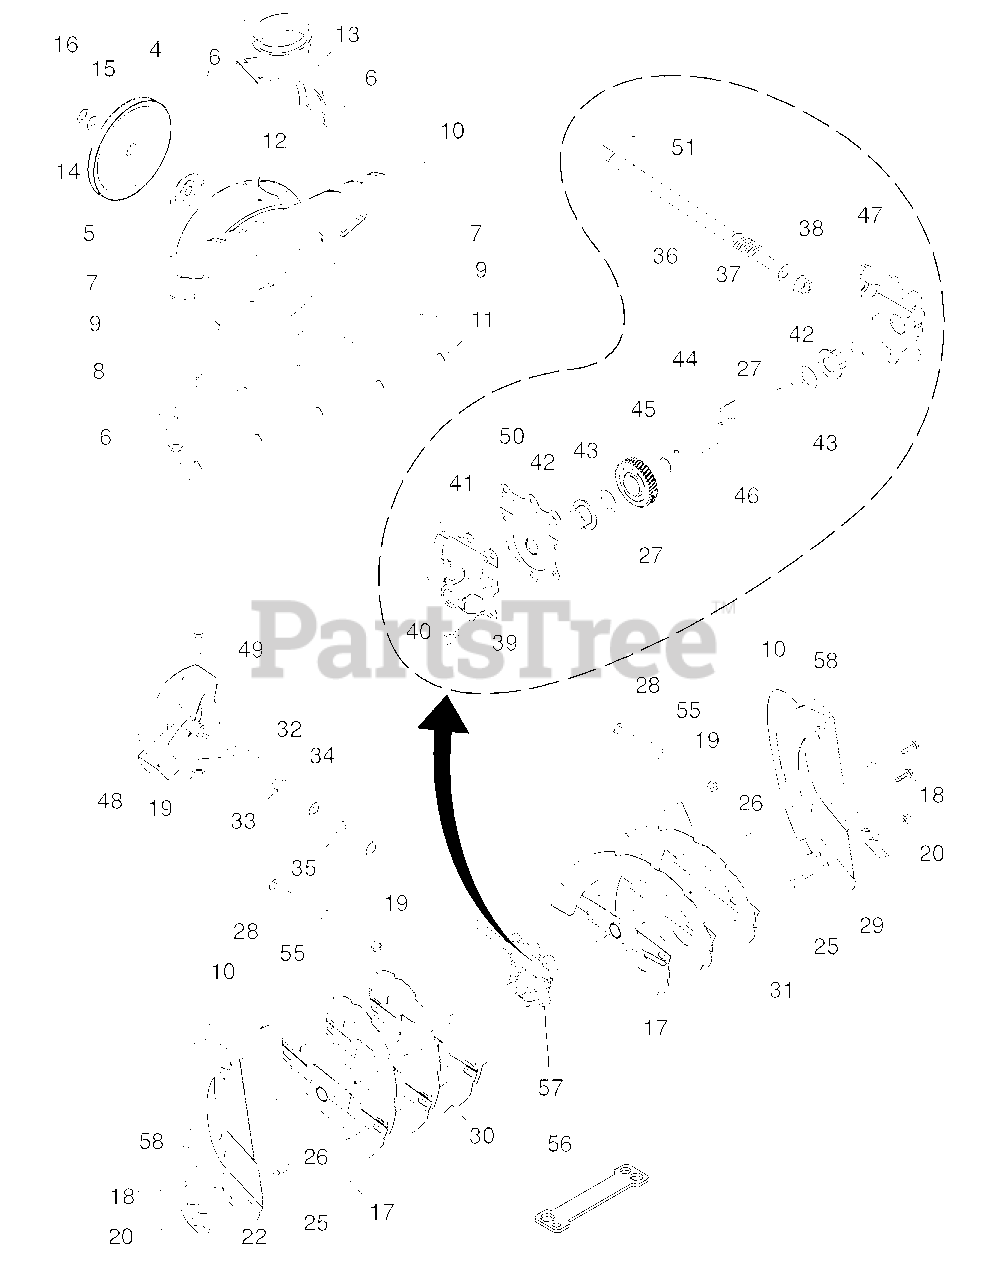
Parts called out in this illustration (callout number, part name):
1	Knob, Lever
2	Screw #10-24 x 5/8
3	Strap, Slotted
4	Nut, Lock 3/8-16
5	Washer, Flat 3/8
6	Control Assembly, Chute Rotater
7	Support, Pivot
8	Screw, Hex Head 5/16-18 x 3/4
9	Knob, Deflector
10	Bolt, Shoulder
12	Nut, Lock 1/4-20
13	Bolt, Carriage 5/16-18
14	Washer, Nylon, Friction
15	Chute Assembly
16	Deflector Assembly
17	Seal, Deflector
18	Rivet, Blind
19	Knob, Speed Control Lever
20	Bolt, Carriage 5/16-18 x 3/4
21	Washer, Flat 5/16
25	Nut, Lock 5/16-18
26	Lever Assembly, Speed Control
27	Retainer, Hairpin
28	Rod, Upper, Speed Control
29	Rod, Lower, Speed Control
30	Clamp, Clean-Out Tool
31	Tool, Clean-Out
33	Washer, Nylon, Friction
34	Screw, Hi-Lo Thread
